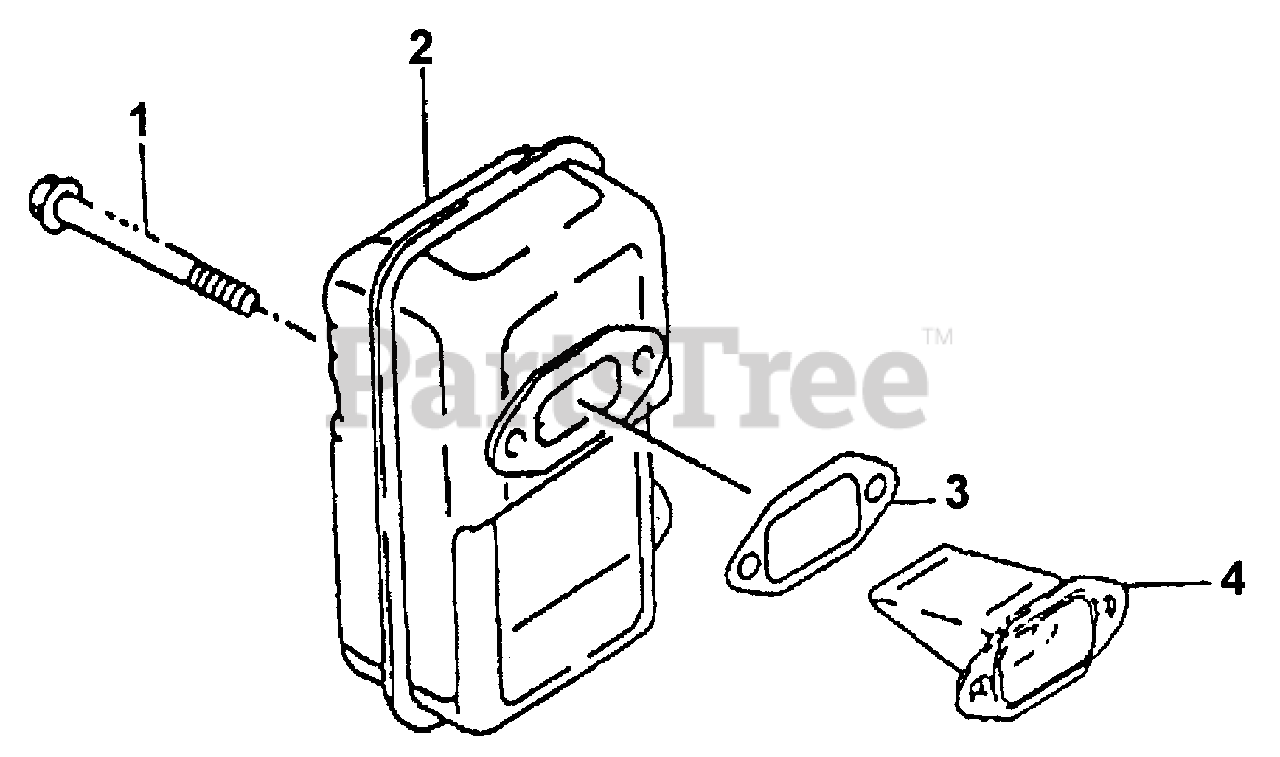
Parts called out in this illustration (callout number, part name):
1	BOLT
2	MUFFLER ASSY.
4	SPARK ARRESTOR
